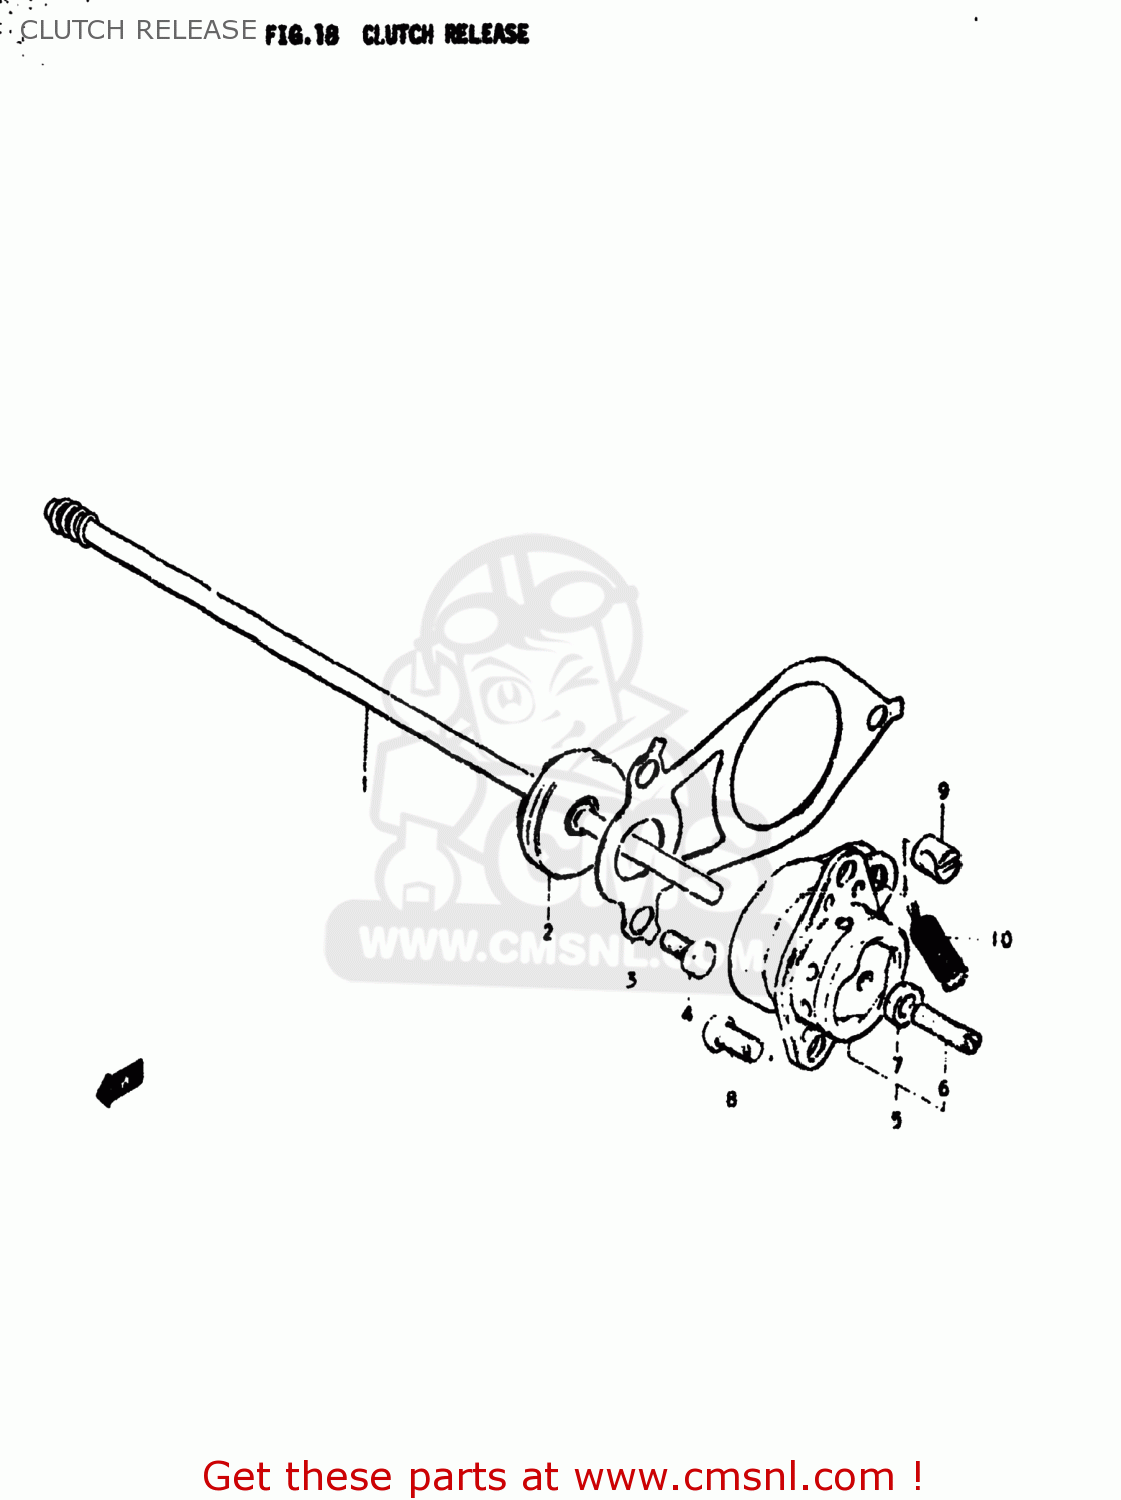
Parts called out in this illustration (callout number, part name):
1	ROD,CLUTCH PUSH
2	OIL SEAL
3	PLATE,CLUTCH PUSH ROD
4	BOLT
5	SCREW ASSEMBLY,CLUTCH RELEASE
6	SCREW
7	NUT 6MM
8	SCREW 6X12
9	PIECE,RELEASE ARM END
10	SPRING
